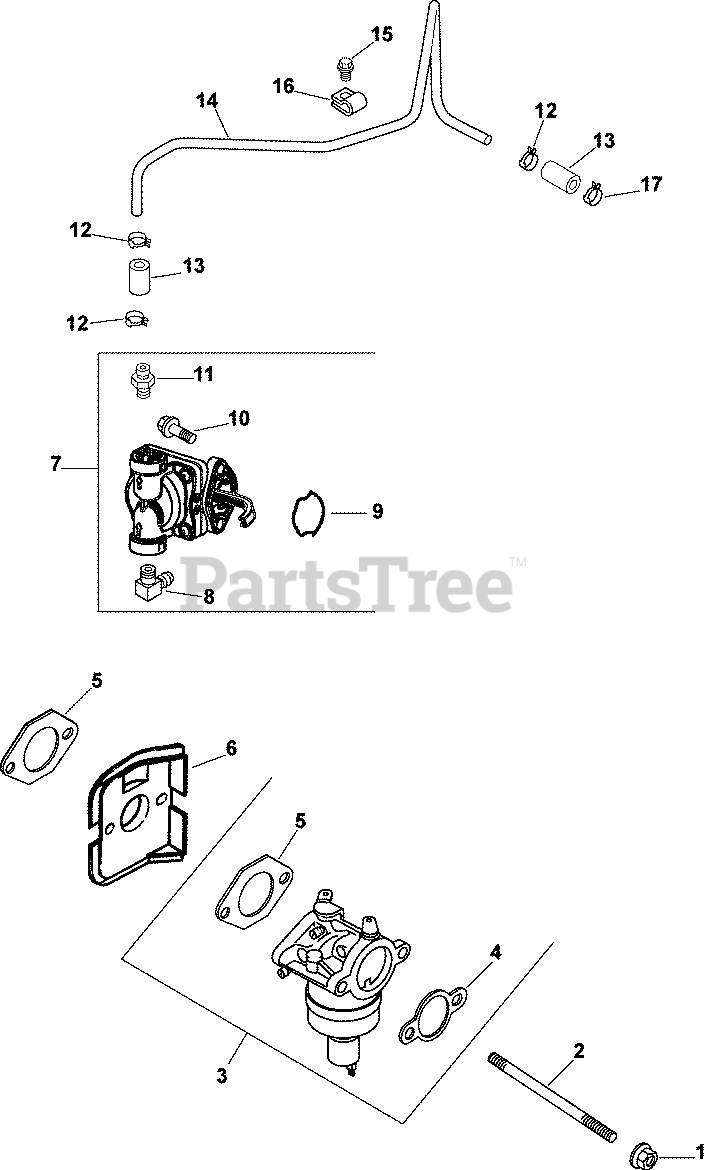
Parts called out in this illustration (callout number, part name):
1	NUT, FLG M6X1.0
2	STUD,M6X1.0X116
3	KIT, CARB W/GASKETS - USE 12 853 169-S
4	GASKET, AIR CLEANER BASE
5	GASKET, CARBURETOR
6	DEFLECTOR, HEAT
7	KIT, FUEL PUMP
8	CONNECTOR, 90 DEG. HOSE
9	O-RING, FUEL PUMP
10	SCREW, LBD SKT M6x1.0x20-(#25086403S)
11	KIT, STRAIGHT FITTING
12	CLAMP, HOSE (KM)-USE 25 237 31-S
13	HOSE,LW PERM.FUEL 24.00"-USE 25 111 81-S
14	LINE, FUEL
15	SCREW, FLG THD FRM M5X.8X10
16	CLIP, TUBE & WIRING (KM)
17	CLAMP, BAND SPRING HOSE-(#2523737S)
